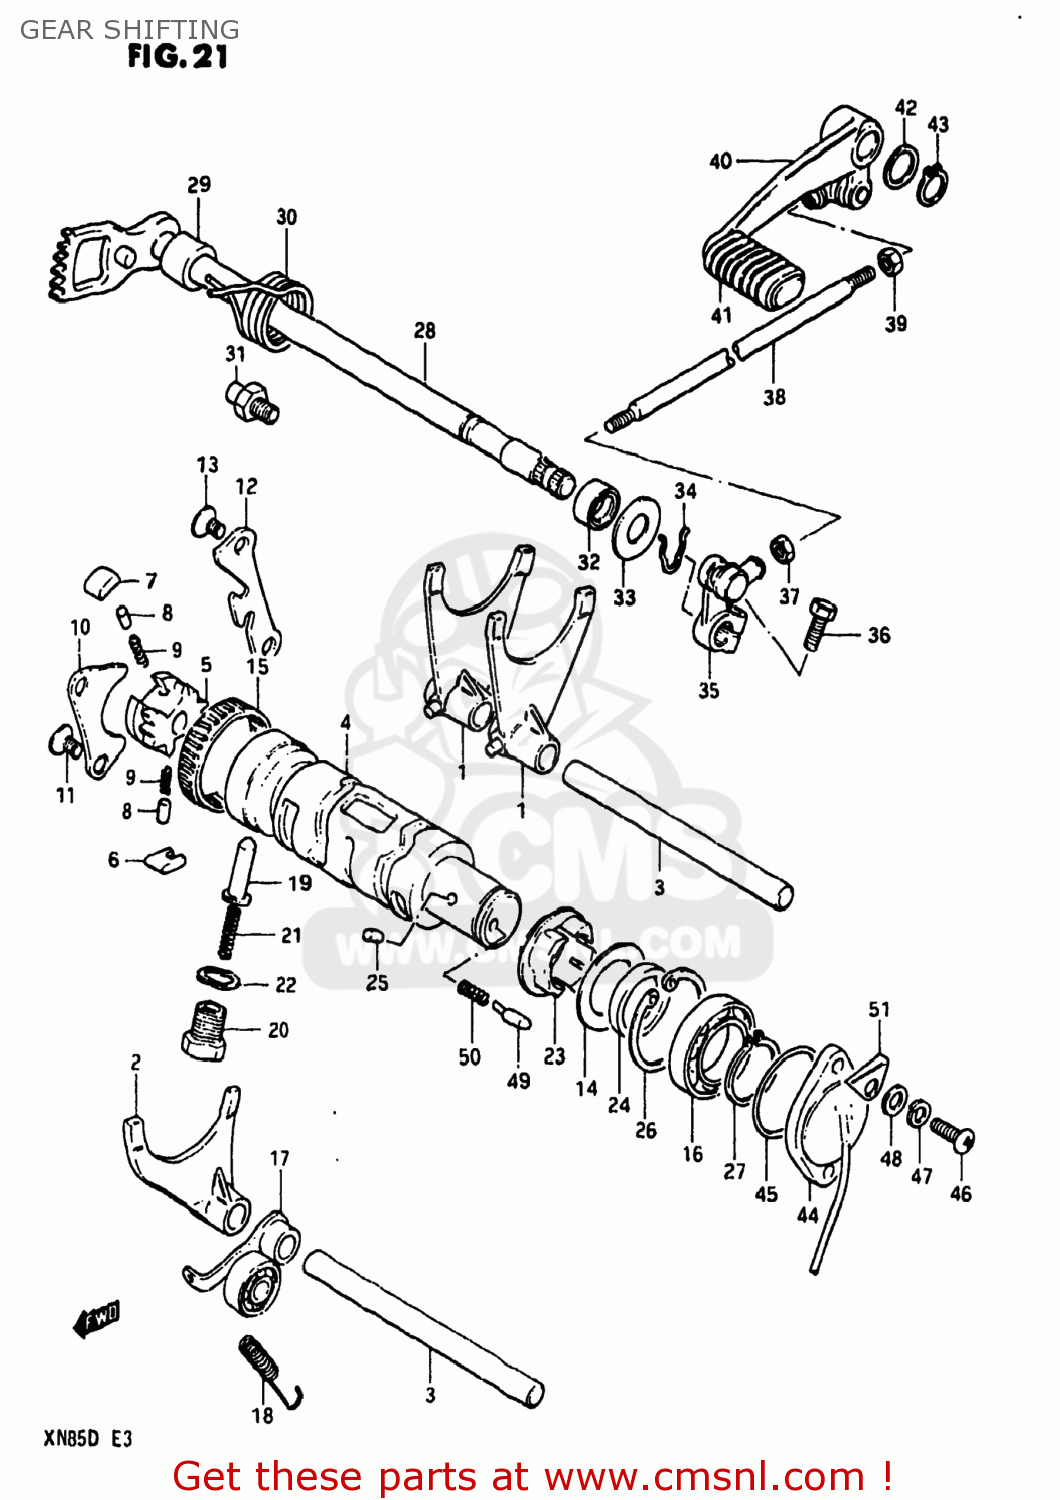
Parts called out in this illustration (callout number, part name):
1	FORK,GEAR SHIFT NO.1
2	FORK,GEAR SHIFT NO.3
3	SHAFT,GEAR SHIFT FORK
4	CAM,GEAR SHIFT
5	RETAINER,GEAR SHIFT CAM
6	PAWL,GEAR SHIFT NO.1
7	PAWL,GEAR SHIFT NO.2
8	PIN(5X8)
9	SPRING
10	LIFTER, PAWL
11	SCREW
12	GUIDE,GEAR SHIFT CAM
13	SCREW
14	WASHER,THRUST
15	BEARING(43X49X12)
16	BALL BEARING
17	STOPPER,GEAR SHIFTING
18	SPRING
19	STOPPER,GEAR SHIFTING
20	HOLDER,GEAR SHIFT CAM STOP SPR
21	SPRING
22	GASKET(14X19.2X2) (NAS)
23	PLATE,GEAR SHIFT CAM STOPPER
24	SPACER
25	PIN 4X6
26	CIRCLIP,42MM
27	CIRCLIP,25MM
28	SHAFT,GEAR SHIFT
29	SPACER(12X20X15.3)
30	SPRING
31	STOPPER,GEAR SHIFT CAM
32	OIL SEAL
33	WASHER (12.5X27X1.6)
34	SPRING,RETAINER
35	ARM,GEAR SHIFT
36	BOLT
37	NUT
38	ROD,GEAR SHIFT LINK
39	NUT
40	LEVER ASSEMBLY,GEAR SHIFTING
41	RUBBER,PEDAL
42	WASHER(12.5X20X1)
43	CIRCLIP
44	TERMINAL BASE,NEUTRAL SWITCH
45	O RING(D:2.4,ID:36.5)
46	SCREW
47	LOCK WASHER
48	WASHER
49	PIN(5X15.5)
50	SPRING
51	CLAMP,WIRING HARNESS
